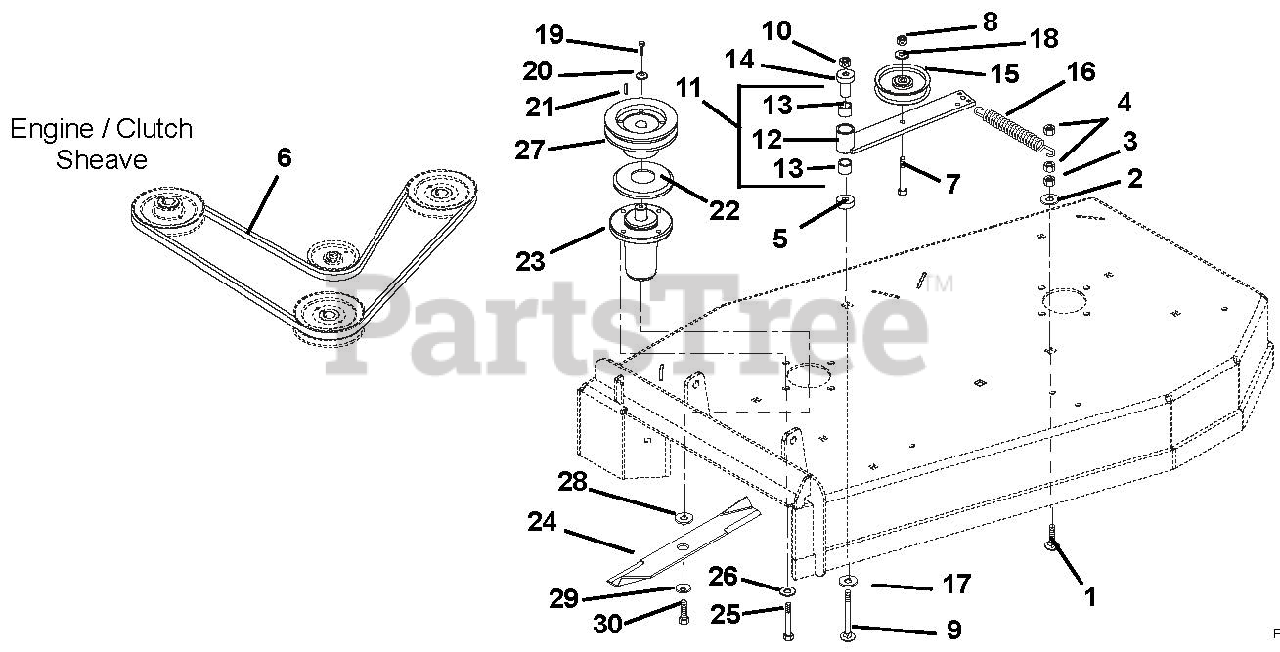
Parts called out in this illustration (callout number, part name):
1	Bolt-Round Head Square Neck .38-16 x 1.50 Grade 5
2	Washer-Locking .38 x .094 Regular
3	Nut-Hex .38-16
4	Nut-Locking-Center .38-16
5	Washer-Flat-Steel .515 x 1.625 x .25
6	V-Belt B-Section 36.70 x .650
6	V-Belt B-Section 35.47 x .650
7	Bolt-Round Head Square Neck .38-16 x 3.00 Grade 5
8	Nut-Locking-Center .38-16
9	Bolt-Round Head Square Neck .50-13 x 3.75 Grade 5
10	Nut-Locking-Center .50-13
11	Assembly, Idler Pivot Arm
12	Weldment, Idler Pivot Arm
13	Bearing, 1.00 x 1.12 x .75
14	Bearing, Pedestal Powdered Metal
15	Idler-Flat 4.00 x .38 2.00 W
16	Spring, Extension
17	Washer-Flat-Steel .755 x 1.375 x .062
18	Seal, Idler Bearing
19	Bolt-Hex .38-16 x 1.00 Grade 8
20	Washer-Cupped-Serrated .375
21	Key, Square .25 x .25 x 1.00 RC 40-50
22	Slinger-Dust
23	Assembly, Maintenance Free Spindle
24	Blade- Mower
24	Blade- Mower 16.25
24	Blade- Mulching
25	Bolt-Hex .38-16 x 1.00 Grade 5
26	Washer-Locking .38 x .094 Regular
27	Pulley
28	Washer, Flat .64 x 1.81 x .250
29	Washer-Bellville .63 x 1.625 x .14
30	Bolt-Hex .62-18 x 1.75 Grade 8
